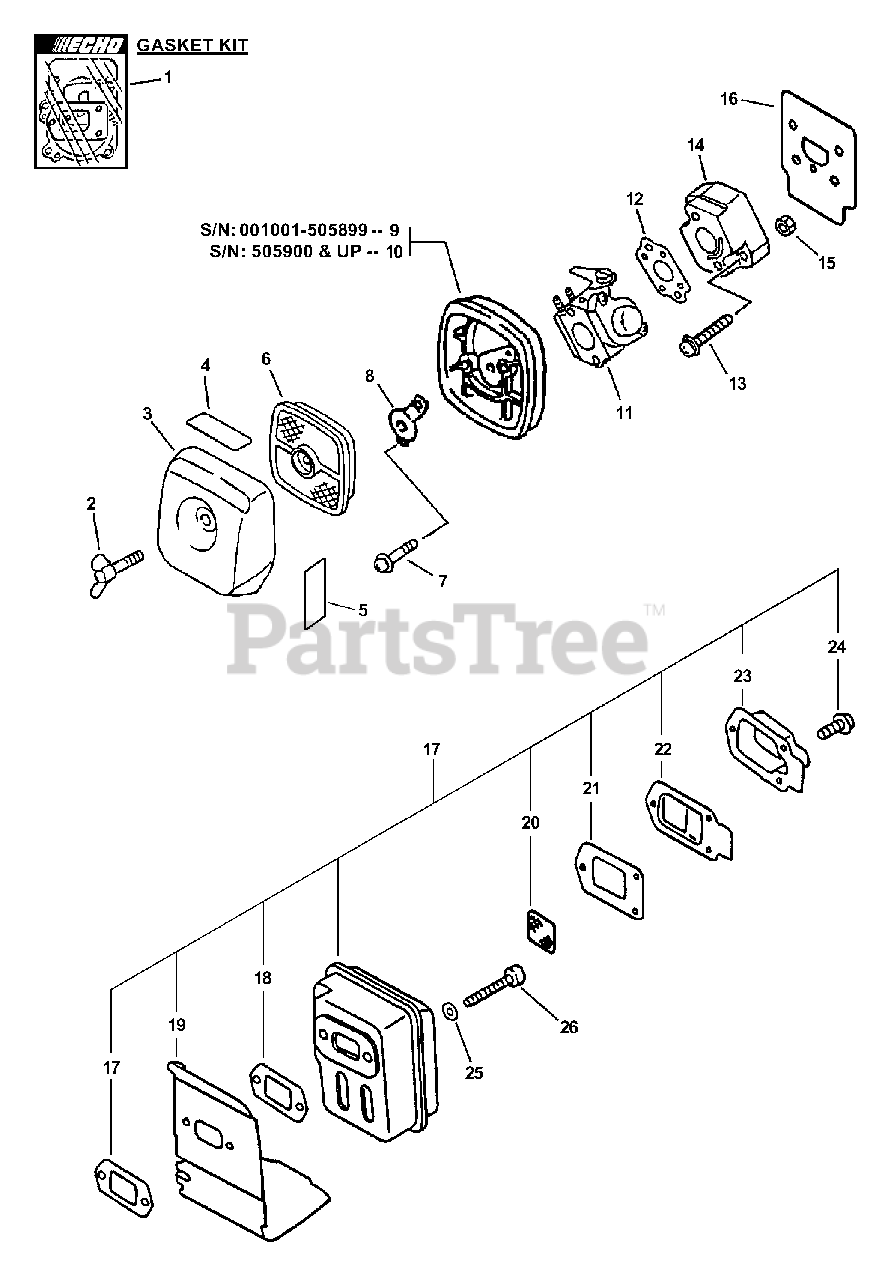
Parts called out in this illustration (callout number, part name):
1	GASKET KIT
2	THUMBSCREW
3	COVER, AIR FILTER - BLACK
4	LABEL - CHOKE
5	LABEL - CHOKE
6	FILTER, AIR - SINGLE LAYER
7	SCREW - 5X65
8	PLATE, PREVENT
9	AIR FILTER CASE ASSY
10	CASE, AIR FILTER
11	CARBURETOR WT-424B
12	GASKET, INTAKE
13	SCREW - 5X20
14	INSULATOR, INTAKE
16	SHIELD, INTAKE
17	MUFFLER ASSY
18	GASKET, EXHAUST
19	COVER, EXHAUST
20	SCREEN, SPARK ARRESTOR
21	GASKET, EXHAUST
22	GASKET, EXHAUST - INNER
23	GUIDE, EXHAUST - OUTER
24	SCREW - 4X10
25	WASHER - 5
26	SCREW - 5X55
